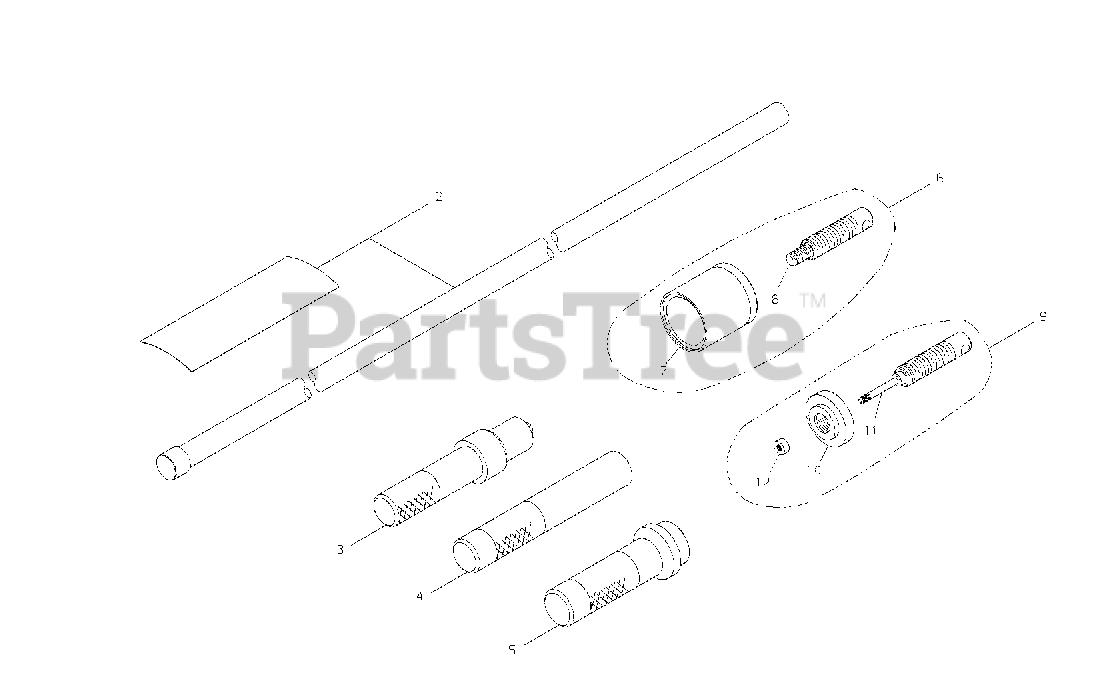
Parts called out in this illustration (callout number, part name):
2	DRIVER ASSY, BUSHING
3	BEARING DRIVER (6000 DDU)
5	BEARING DRIVER (6202)
6	PULLER ASSY
7	HOLDER
8	PULLER BOLT
9	PULLER ASSY
10	HOLDER
